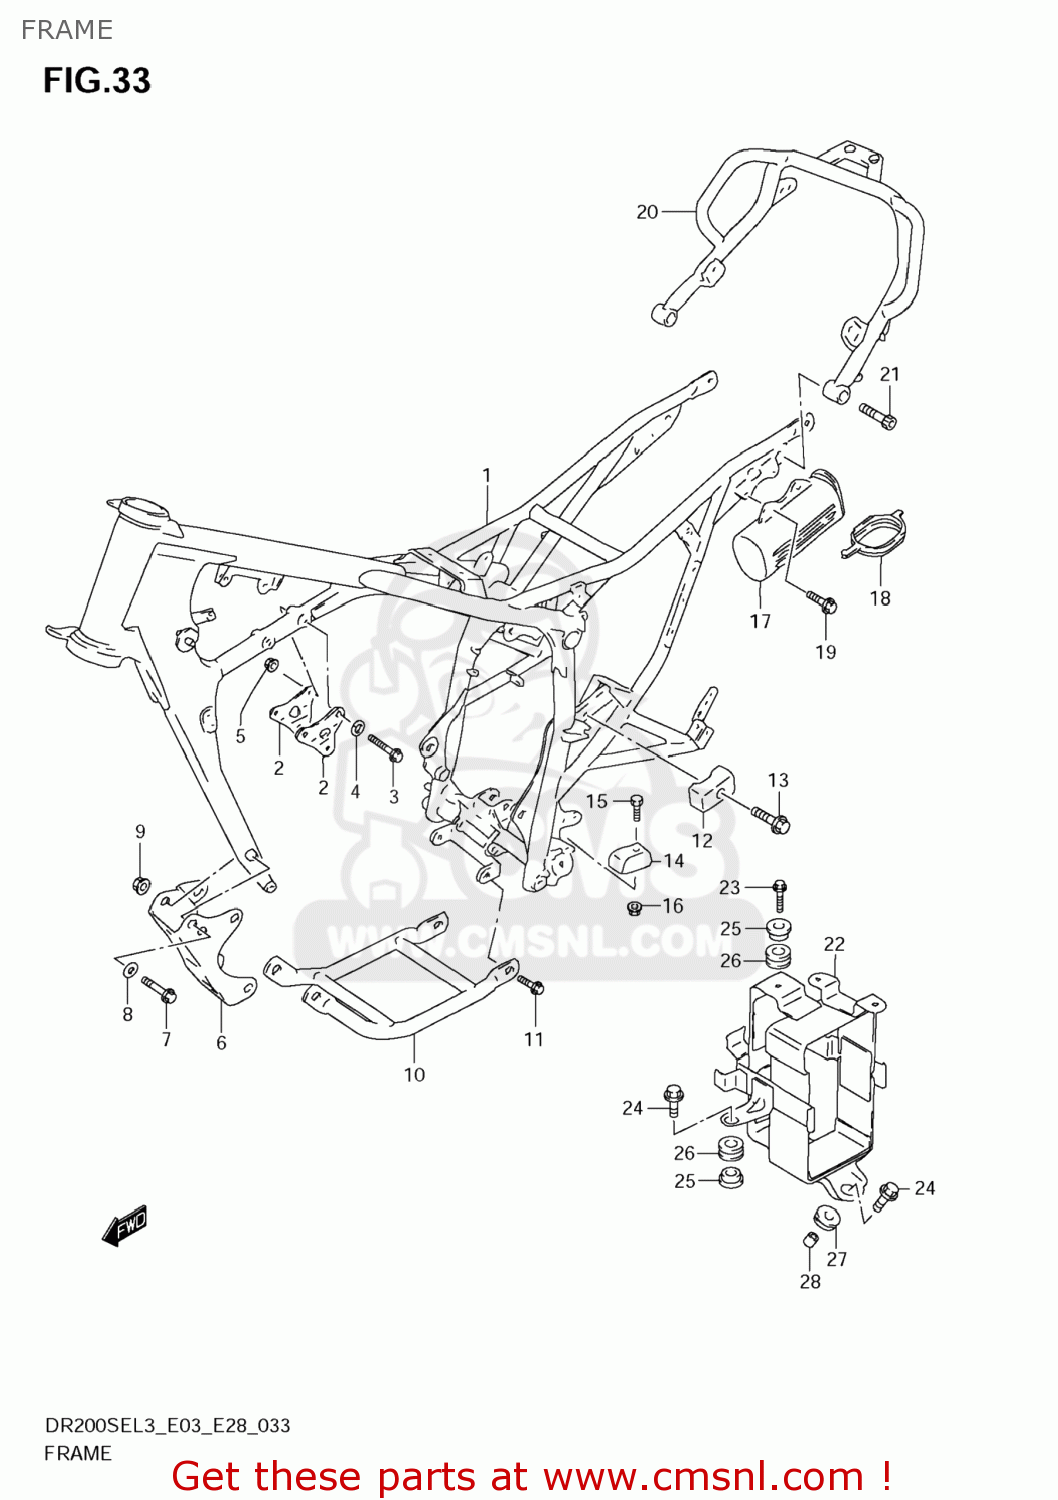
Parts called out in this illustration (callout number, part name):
1	FRAME(GRAY)
2	PLATE,ENGINE MOUNT UPR
3	BOLT(8X53)
4	WASHER,LOCK
5	NUT
6	PLATE,ENG MTG LWR
7	BOLT(8X70)
8	WASHER,LOCK
9	NUT
10	PROTECTOR,ENGINE(GRAY)
11	BOLT
12	GUIDE,CH CONTROL UPR
13	BOLT
14	GUIDE,CHAIN CONTROL LWR
15	BOLT(6X20)
16	NUT
17	HOLDER,TOOL
18	CAP,HOLDER
19	BOLT(6X16)
20	GRIP,RR
21	BOLT(8X30)
22	HOLDER,BATTERY
23	BOLT
24	BOLT(6X25)
25	WASHER
26	CUSHION
27	CUSHION
28	SPACER(6.5X10X9)
